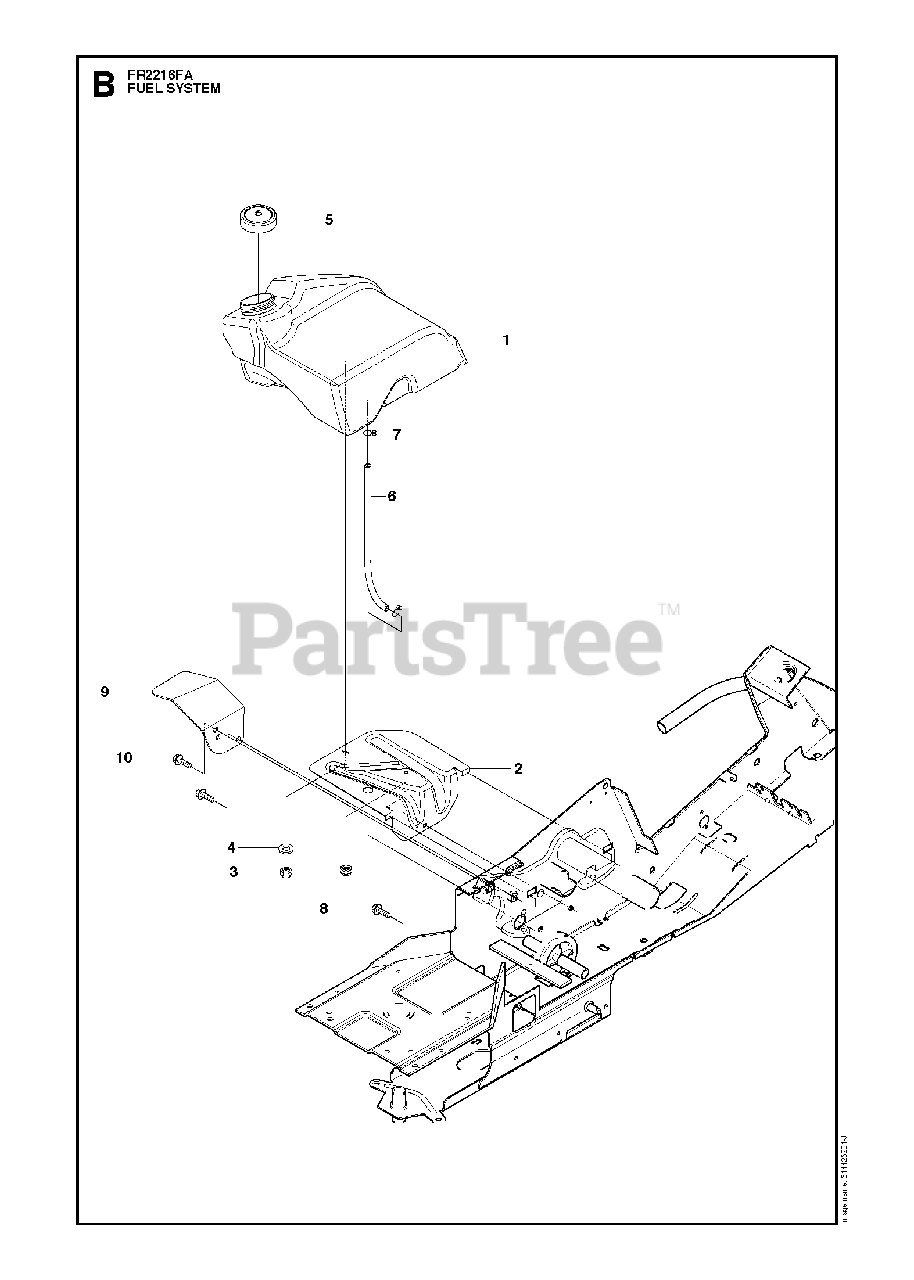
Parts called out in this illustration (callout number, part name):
3	LOCKNUT M6
4	WASHER
10	SCREW M10X25
